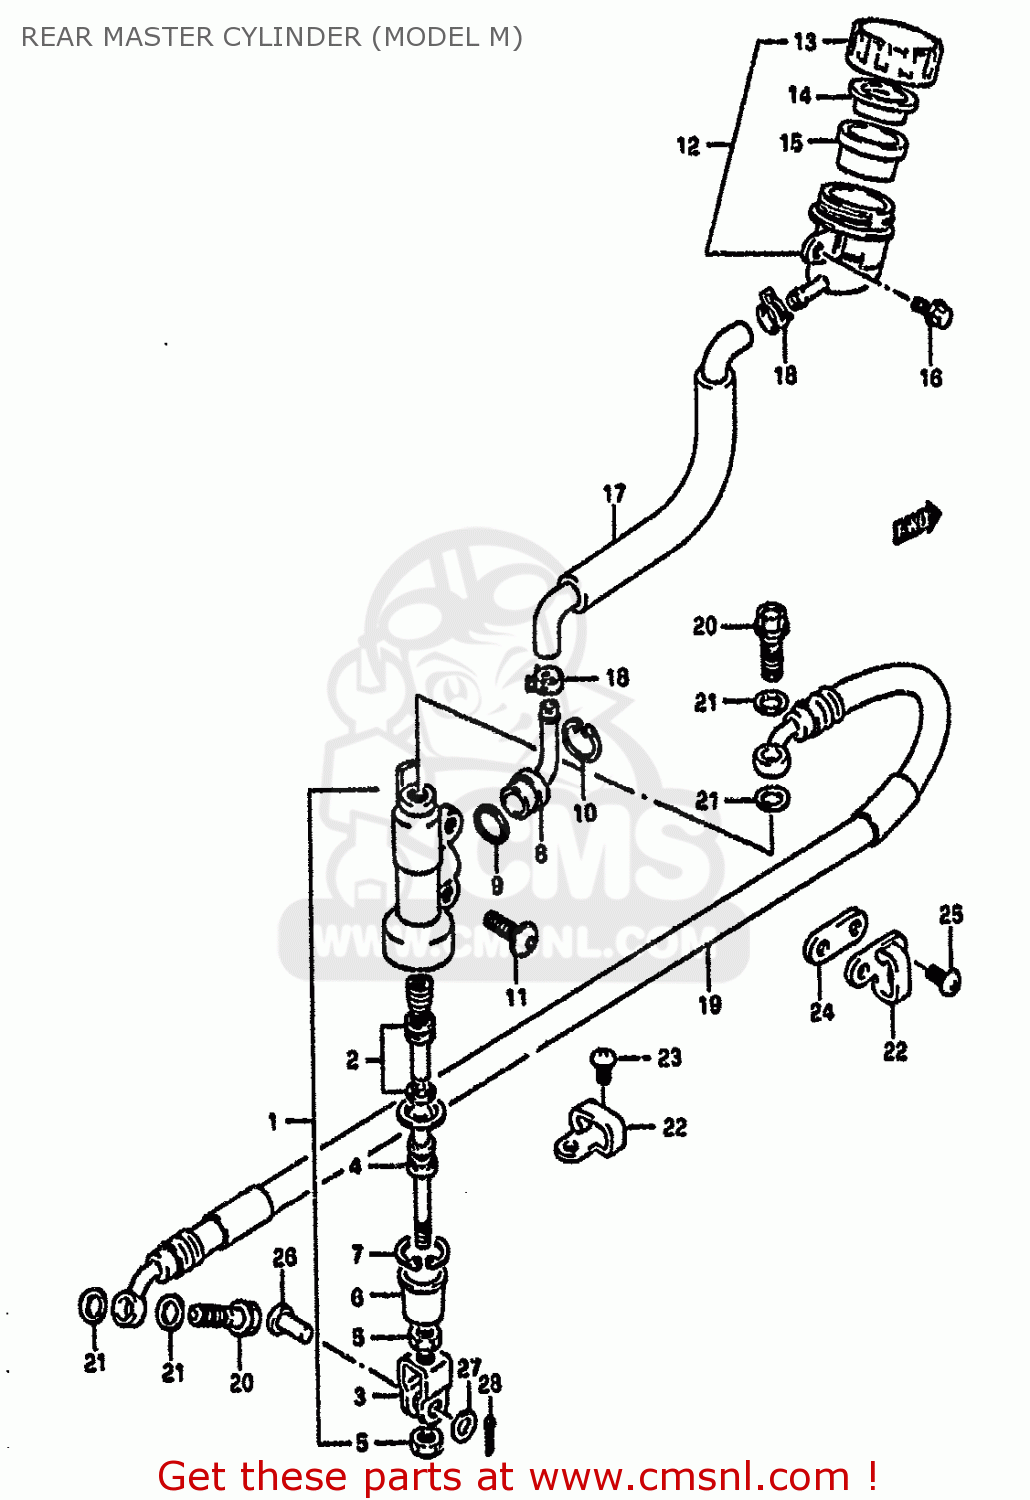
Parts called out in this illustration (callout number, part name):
1	CYLINDER ASSEMBLY,REAR MASTER
2	PISTON/CUP SET
3	YOKE
4	ROD,PUSH
5	NUT
6	BOOT
7	CIRCLIP
8	CONNECTOR
9	O RING
10	CIRCLIP
11	SCREW(6X16)
12	TANK ASSY,RR BRAKE RESERVOIR
13	CAP
14	PLATE
15	DIAPHRAGM
16	BOLT
17	HOSE,TANK
18	CLAMP,RESERVOIR HOSE
19	HOSE,REAR BRAKE
20	BOLT UNION
21	WASHER(10X15X1.5)
22	GUIDE,RR BRAKE HOSE
23	SCREW(5X10)
24	SEAT,RR BRAKE HOSE GUIDE
25	SCREW
26	PIN(8X20)
27	WASHER(8.5X13X1.6)
28	PIN
